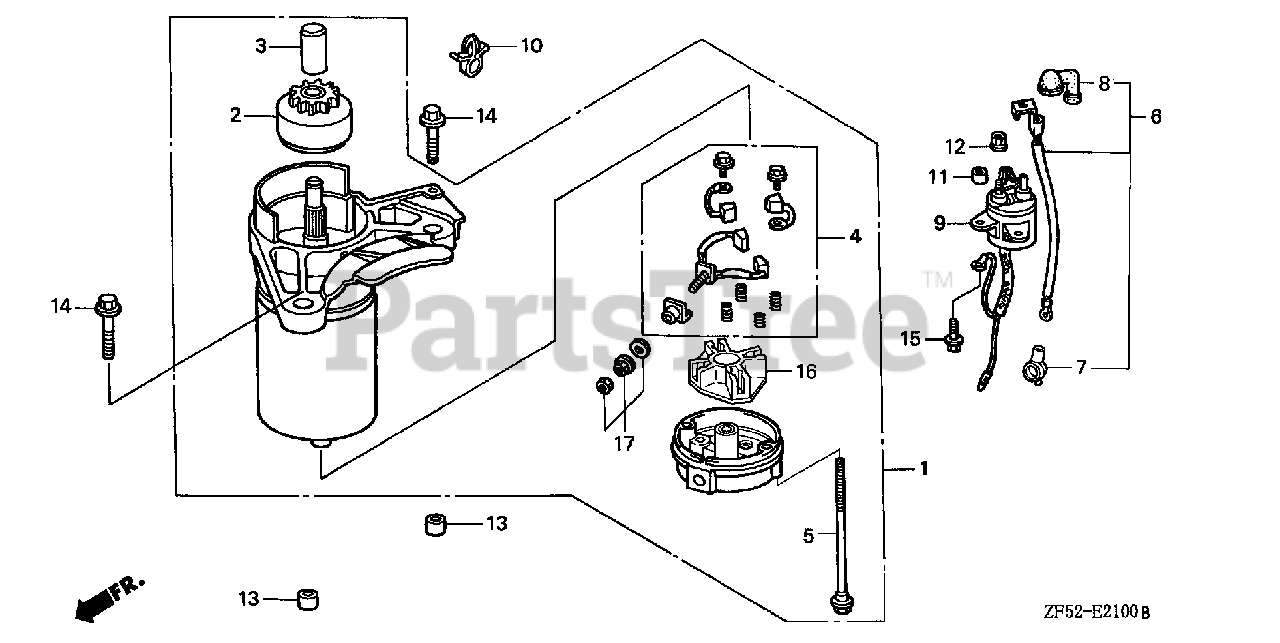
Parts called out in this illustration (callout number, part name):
1	STARTER MOTOR ASSY.
2	DRIVE ASSY.
3	STOPPER SET, PINION
4	BRUSH SET
5	BOLT, THROUGH
13	PIN, DOWEL (10X12)
14	BOLT, FLANGE (8X35)
